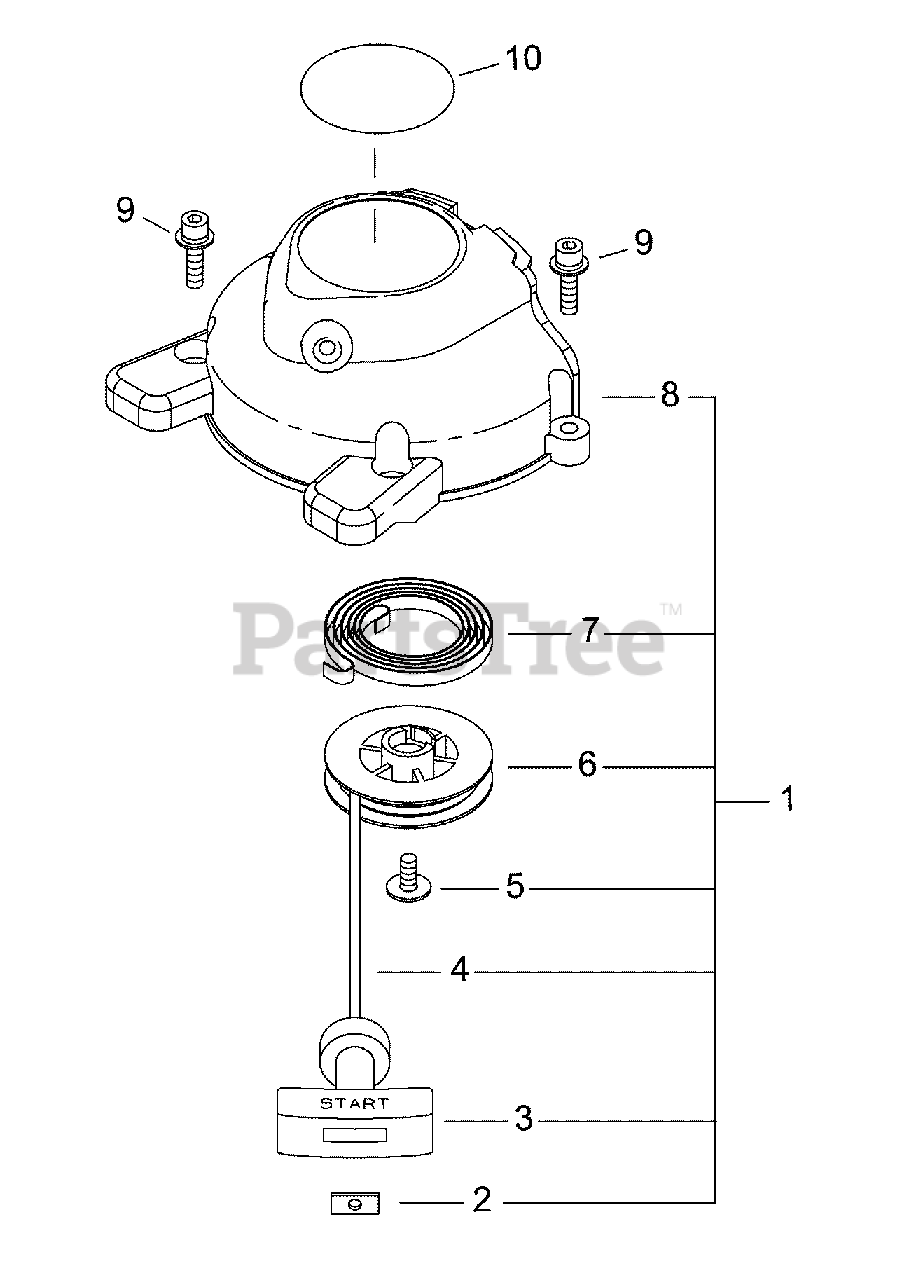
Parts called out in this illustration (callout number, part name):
1	STARTER ASSY, RECOIL
2	RETAINER, ROPE
3	GRIP, STARTER
4	ROPE, STARTER
5	SCREW 5
6	REEL, ROPE
7	SPRING, RECOIL
8	CASE, RECOIL STARTER
9	BOLT, ADHESIVE M5×20
10	LABEL, SWISHER E4
